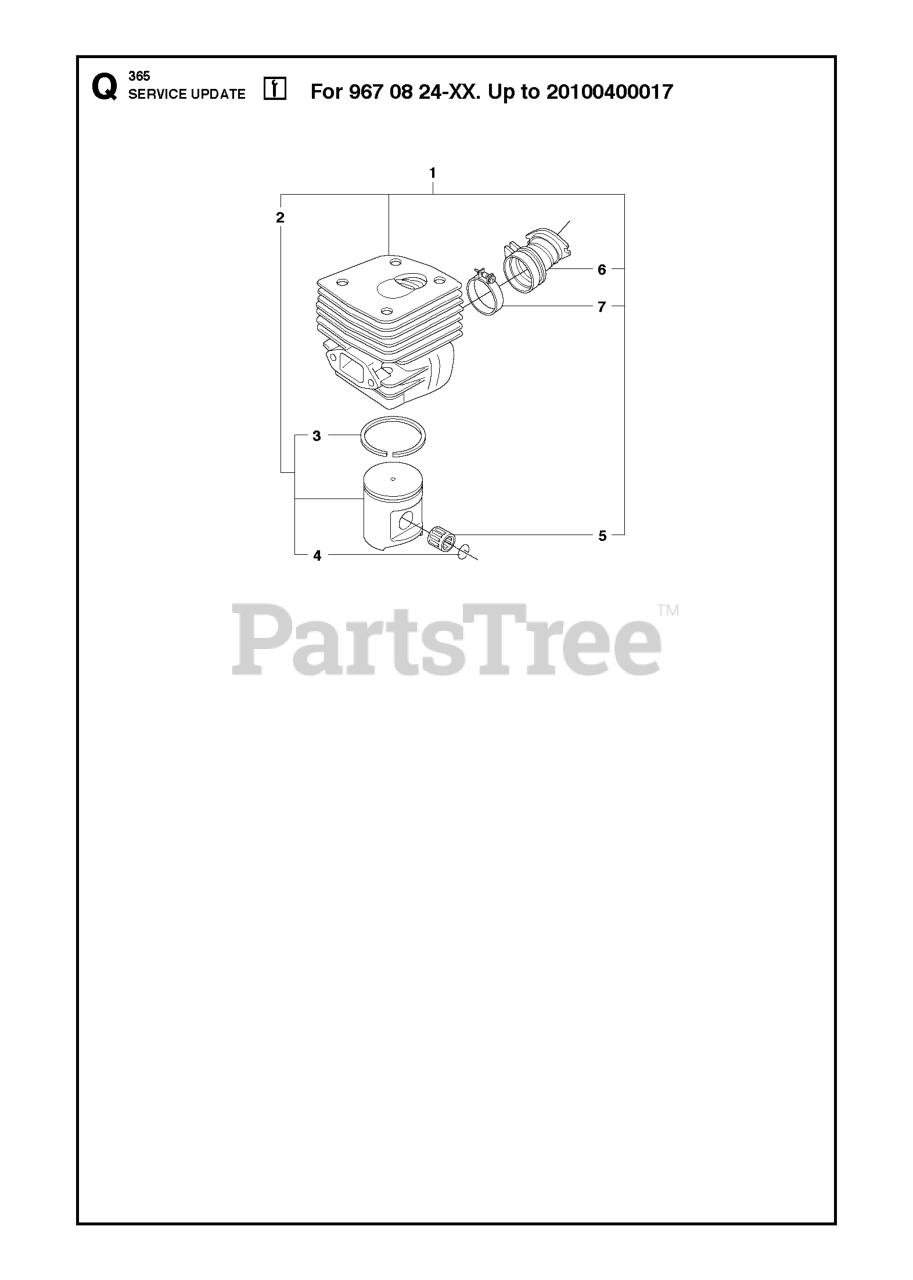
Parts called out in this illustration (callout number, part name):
1	CYLINDER
2	PISTON CPL 48 MM
3	PISTON RING
4	WRIST PIN CLIP
5	SUPPORT BUSHING
6	INTAKE PIPE - EPA
7	CLAMP
